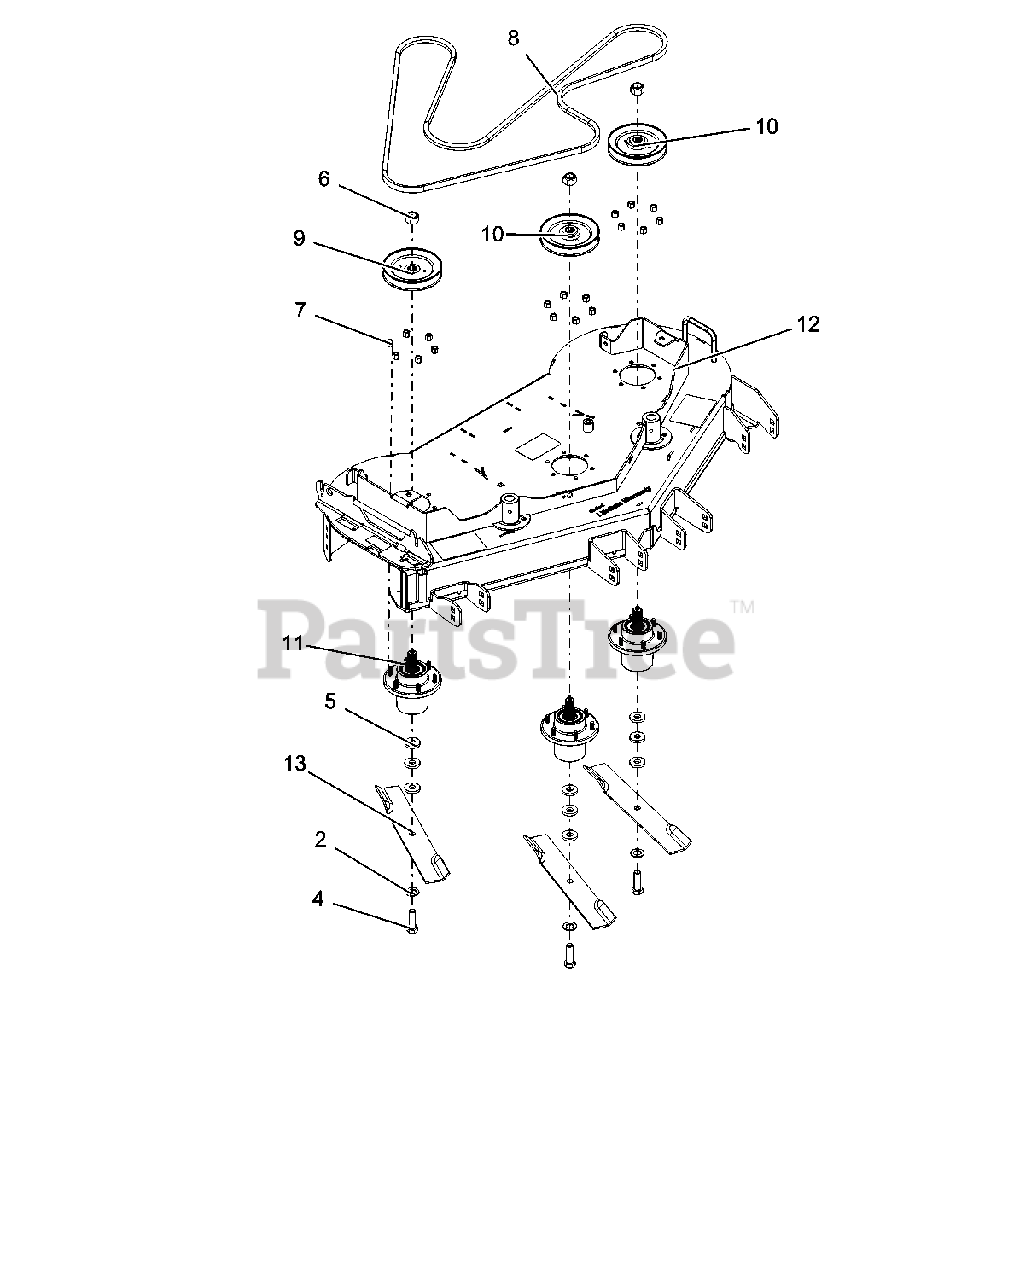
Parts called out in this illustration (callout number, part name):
2	WASHER, .75X1.3125X.120
4	BLT-HEX .62-11X2.00 GR8 YWZC
5	WSHR-FL-STL .630X1.50X.25 YWZC
6	LOCKNUT, 3/4-16 CROWN GR5 Y
7	NUT-LK-NYL .38-16 YWZC
8	BELT, HB
9	PULLEY, SPINDLE 5.75 X .76-BLACK
10	PULLEY, SPINDLE 5.75 X .25-BLACK
11	ASSY, SPINDLE HOUSING
12	ASSY, 48 FLWLKDECK W/DECALS
13	BLADE, 16.50 LO-LIFT
